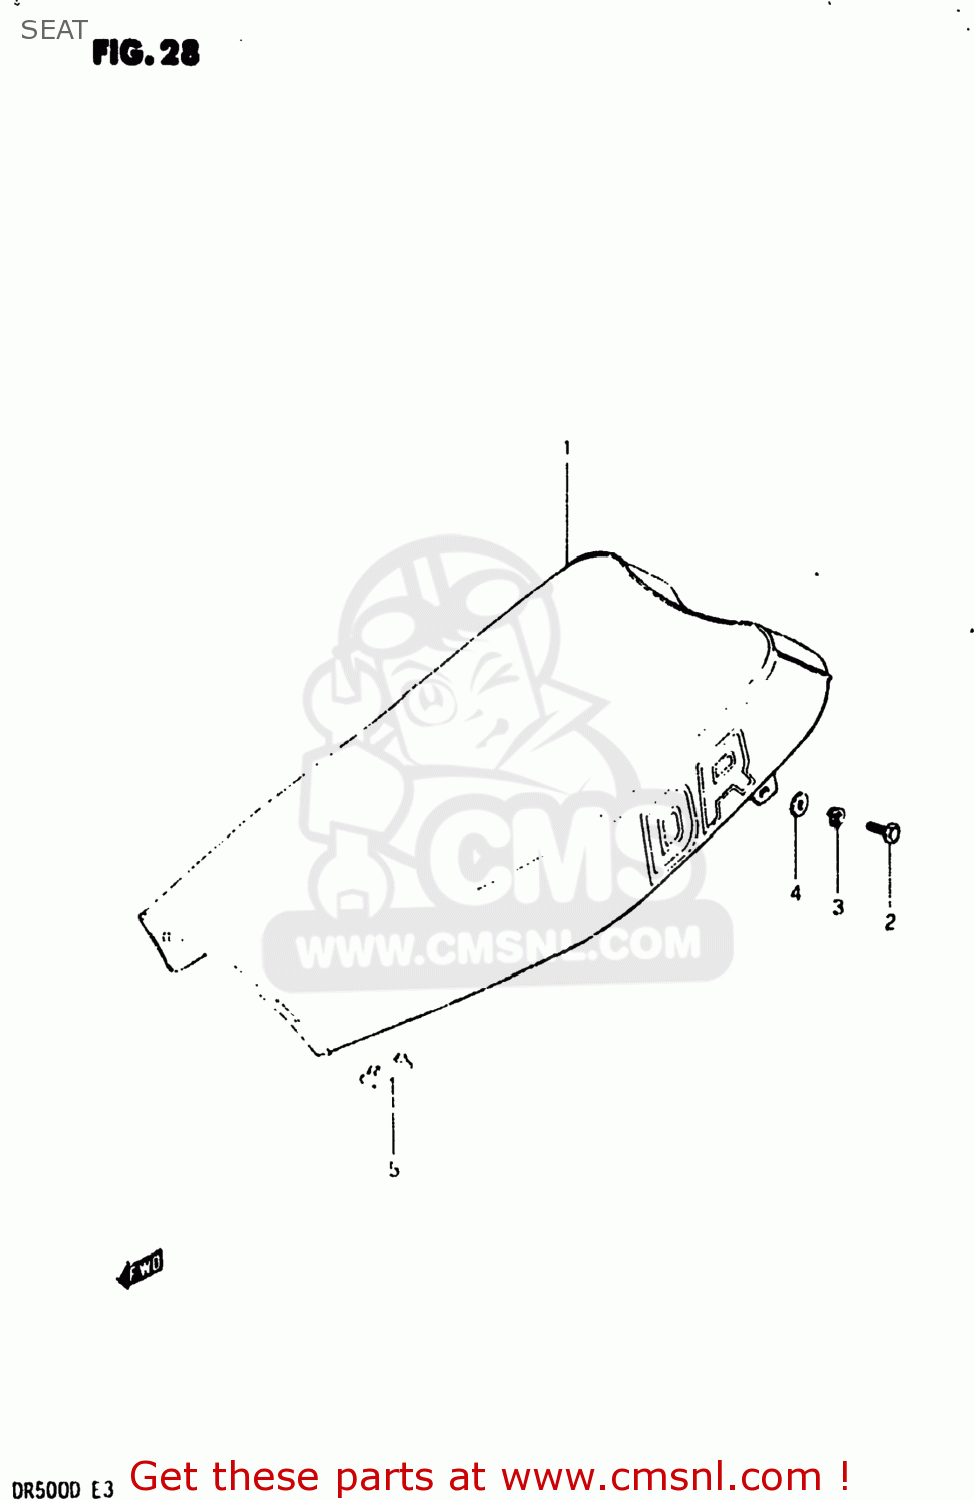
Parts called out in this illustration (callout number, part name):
1	SEAT ASSEMBLY
2	BOLT
3	WASHER,LOCK,8.
4	WASHER
5	CUSHION
